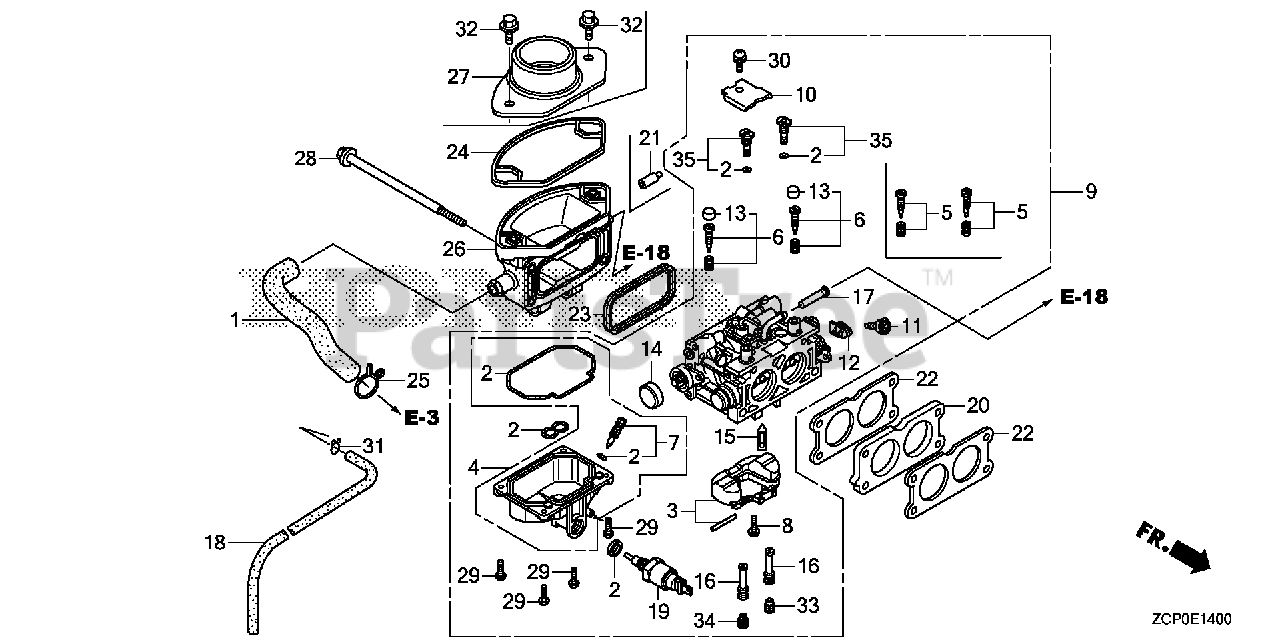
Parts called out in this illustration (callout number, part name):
1	TUBE, BREATHER
2	GASKET SET
4	CHAMBER SET, FLOAT
6	SCREW SET (CARBURETOR NO.)
7	SCREW SET, DRAIN (ADVENTURE GREEN) (CARBURETOR NO.)
8	SCREW, FLOAT
9	CARBURETOR ASSY. (BK05D C)
11	SCREW, THROTTLE STOP
12	ARM, THROTTLE LINKAGE
13	CAP, ADJUSTING SCREW (CARBURETOR NO.)
14	CAP, CHOKE LEVER DUST
15	VALVE, FLOAT
16	NOZZLE, MAIN
17	SCREEN, FUEL STRAINER
18	TUBE, DRAIN
19	VALVE ASSY., SOLENOID
20	INSULATOR, CARBURETOR
22	GASKET, CARBURETOR
23	GASKET, AIR CLEANER
24	SEAL, AIR CLEANER HOUSING
25	CLIP, BREATHER TUBE
26	ELBOW, AIR CLEANER
28	BOLT, FLANGE (6X106)
29	SCREW, PAN (4X12)
30	SCREW-WASHER (5X10)
31	CLIP, TUBE (B8)
33	JET, MAIN (#105) Use from Engine SN BE87H A.
33	JET, MAIN (#110) (CARBURETOR NO.)
33	JET, MAIN (#118)
34	JET, MAIN (#105) Use from Engine SN BE87H A.
34	JET, MAIN (#110) (CARBURETOR NO.)
34	JET, MAIN (#118)
35	JET SET, PILOT (#45)
